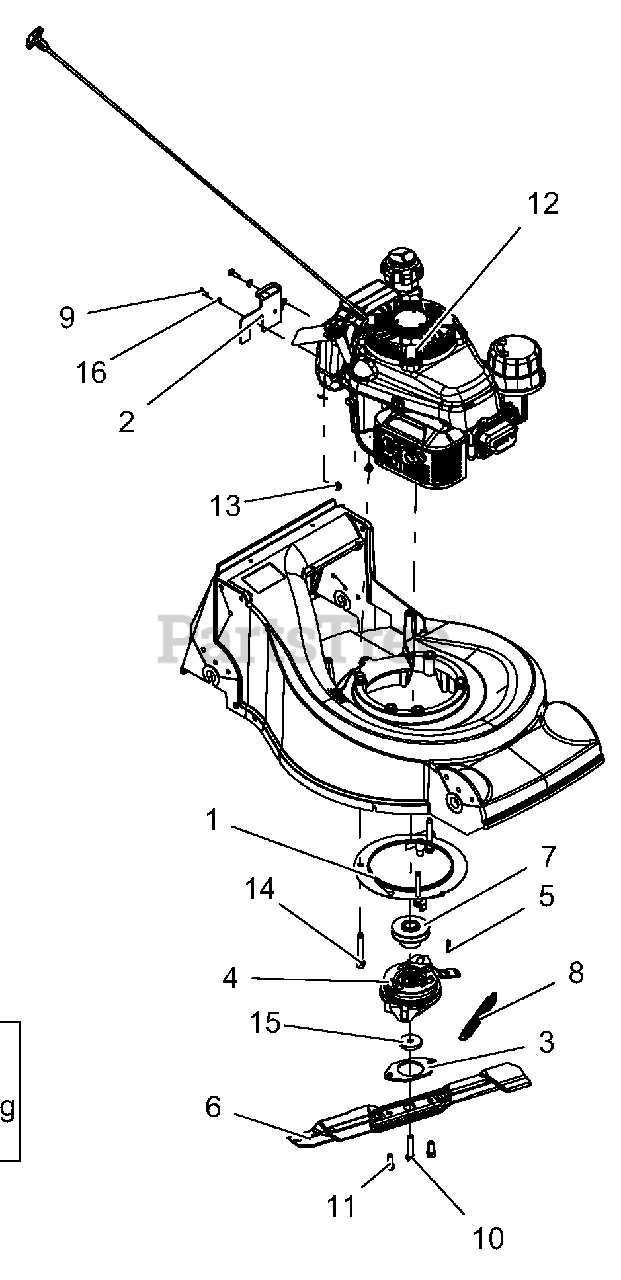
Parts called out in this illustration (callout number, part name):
1	WLDMT, PLATE -BBC
2	BRKT, FUEL TANK
3	SPCR, BBC BLADE
4	KAWASAKI, BBC
5	KEY 3/16 X 3/16 X 1
6	BLADE, MOWER 21" HIGH-LIFT
7	PULLEY, SP, KAWI, BBC
8	SPRG, EXTENSION BBC
9	BLT-HEX .25-20X.75 GR5 YWZC
10	BLT-HEX .38-24X2.00 YWZC GR8
11	BLT-HEX M10 X 1.5X20 GR5 YWZC
12	ENGINE, KAWASAKI BBC - 49ST
13	NUT, LK-TOP-FLG .25-20 YWZC
14	SCR-TAP.375-16X2.75 HWH TR YZ
15	WSHR-FL-STL .400X1.75X.250
16	WSHR-FL-STL.250X.562X.049YWZC
